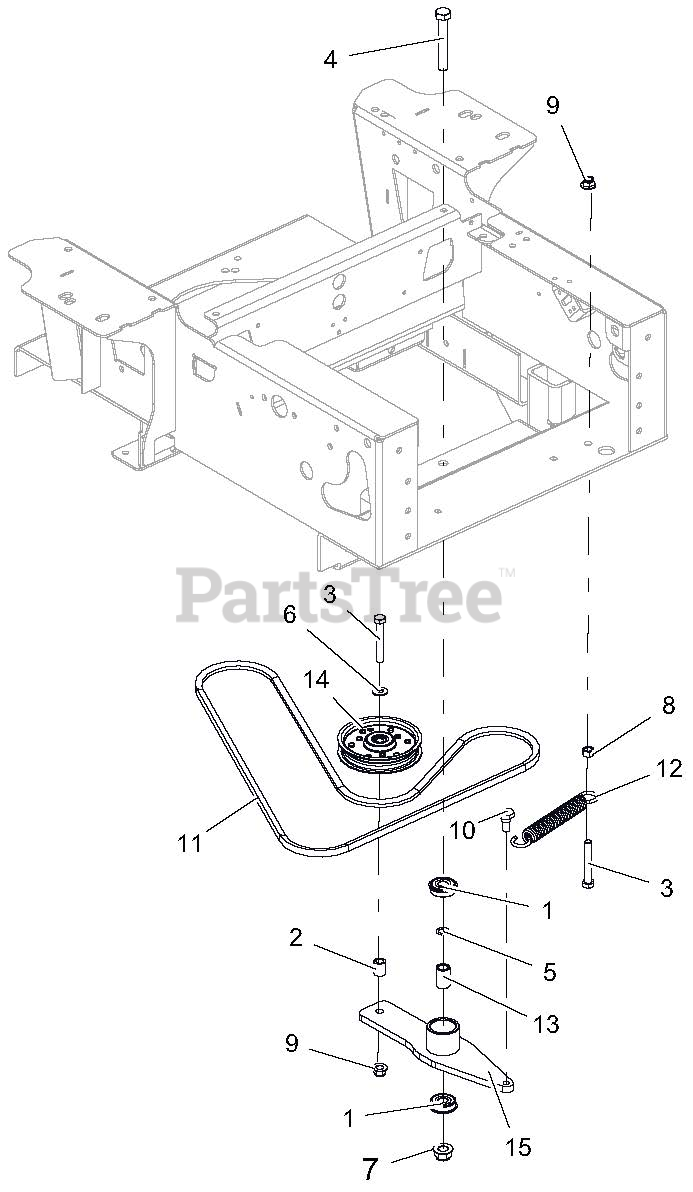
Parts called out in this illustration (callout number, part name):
1	BRG, BALL .501 X 1.38 X .438 SEALED
2	BSHG-SLV .407X.625X.750
3	BLT-HEX .38-16X2.50 GR5 YWZC
4	BLT-HEX .50-13X3.25 GR5 YWZC
5	WASHER-FLAT-STL, .500 X .750 X .020
6	WSHR-FL-STL.406X.812X.065 YWZ
7	NUT-LK-NYL-FLG .50-13 YWZC
8	NUT-HEX .38-16 YWZC
9	NUT-LK-NYL-FLG .38-16 YWZC
10	BLT, SHLDR EP .38-16X.30 HEX YZ
11	BELT, V-A-COGGED
12	SPRG, EXTENSION
13	SPACER, .510 X .750 X 1.148
14	ASM, IDLER 4"
15	WLDMT, HYDRO DRIVE IDLER ARM-BLACK
